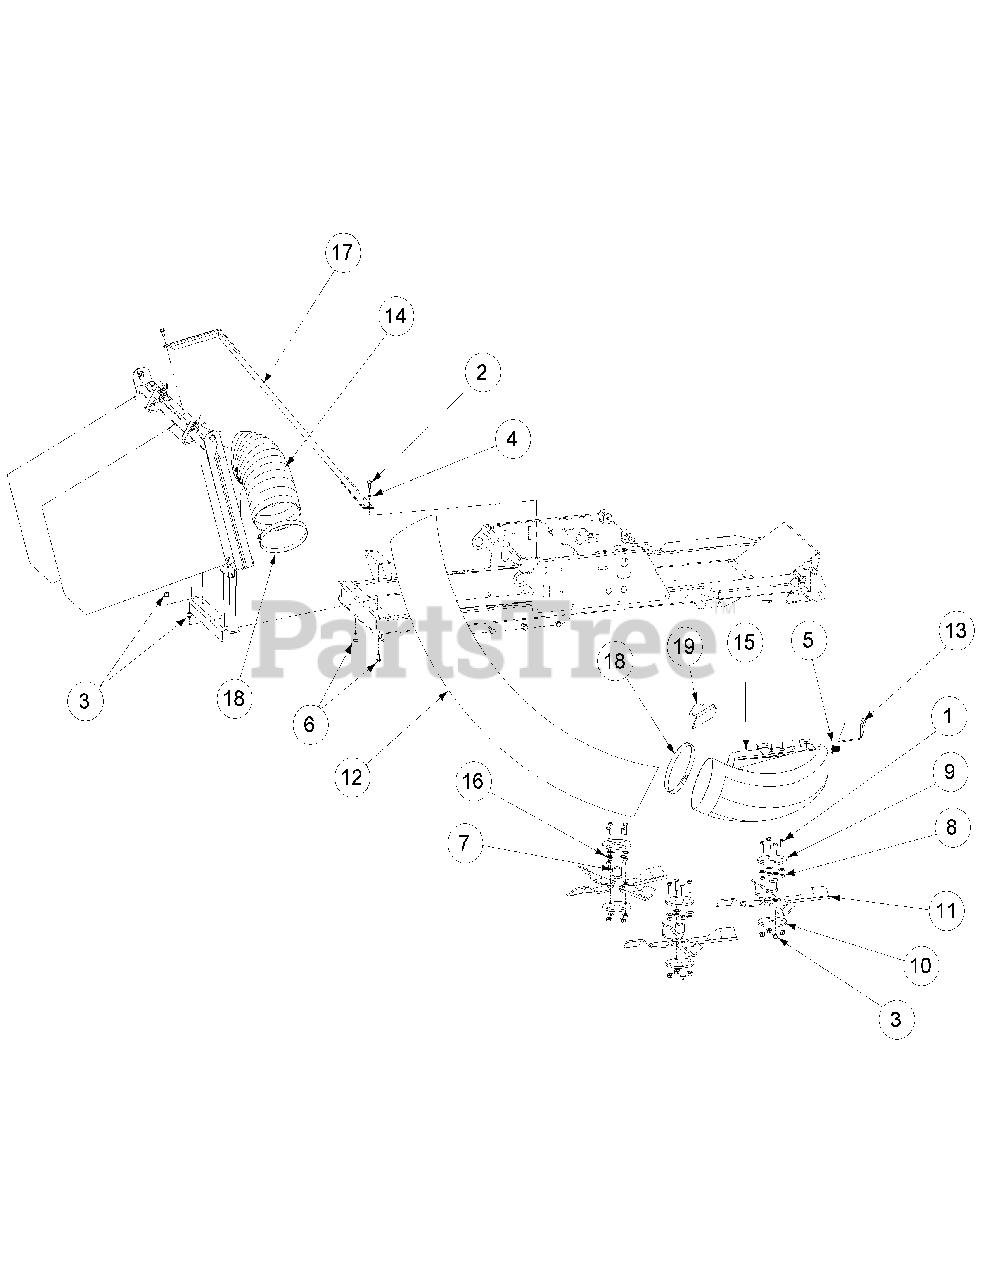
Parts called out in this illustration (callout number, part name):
1	Hex Cap Screw, 3/8-16 x 1-1/4
2	Hex Cap Screw, 5/16-18 x 1.00
3	Flange Lock Hex Nut, 3/8-16
4	Washer, 5/16
5	Carriage Bolt, 3/8-16 x 1.00
6	Hex Cap Screw, 3/8-16, .750
7	Blade Spacer
8	Spacer, .385 ID x .625 OD x .25
9	Mulch Blade Mounting Plate, Top
10	Mulch Blade Mounting Plate, Bottom
11	High Lift Blade
13	MCS Discharge Baffle
14	Double Bagger Assembly
15	Boot Assembly includes:
16	Washer, 1" OD x .625" ID x .048
17	Strut Support Weldment
19	Chute Discharge Baffle
